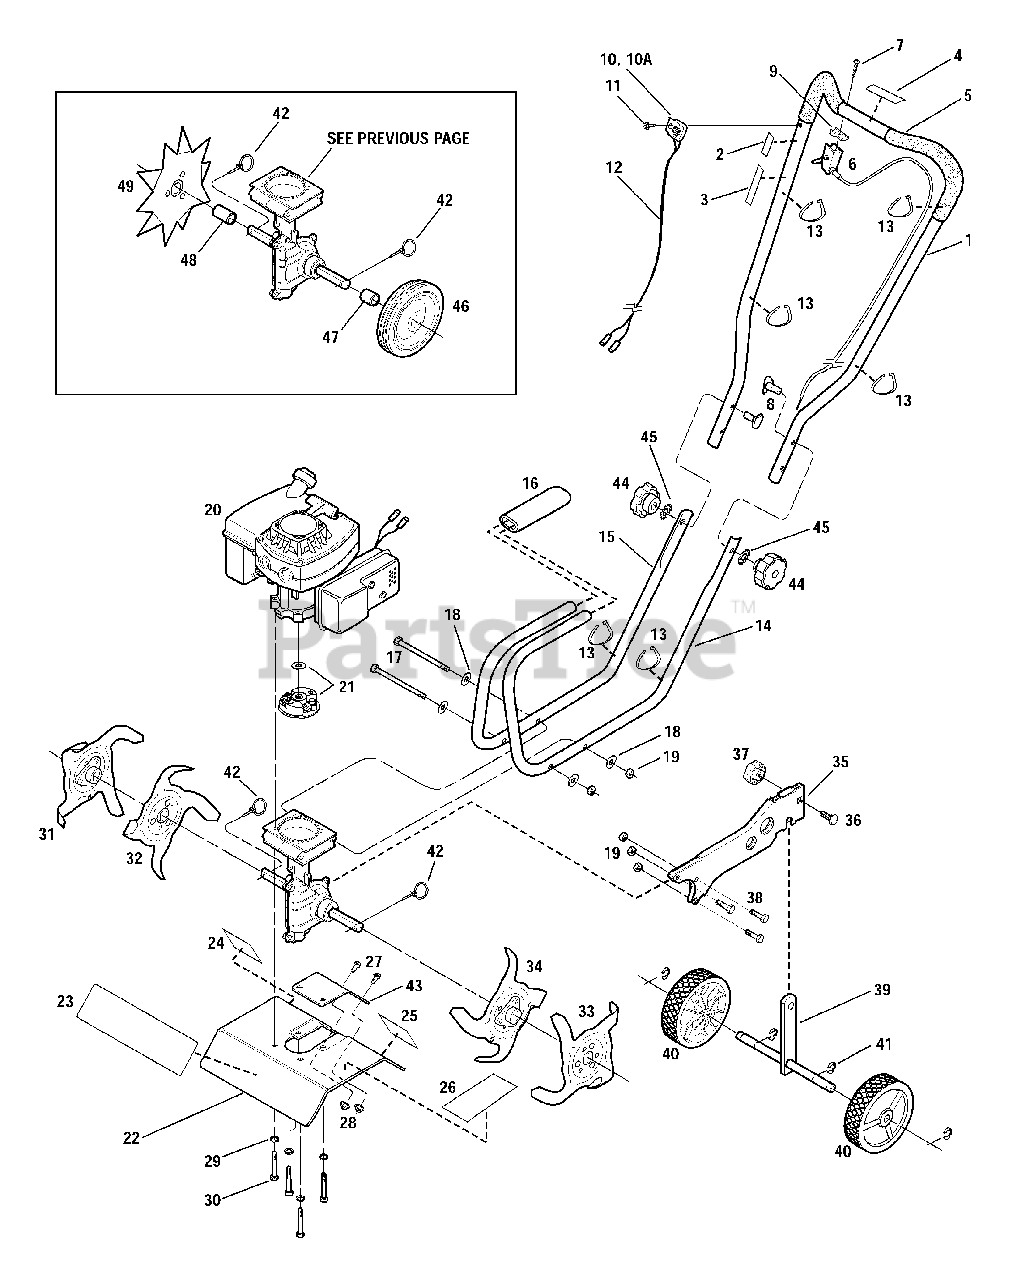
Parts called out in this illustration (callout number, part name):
1	Handlebar Assy.
2	Decal - On/Off Ignition Switch
3	Decal - Starting Stabilization
4	Decal - Throttle Lever Operation
5	Handlebar Grip, PVC
6	Throttle Lever and Cable
7	Pan Hd. Screw, #10-16 x 1-1/2
8	Saddle Hd. Screw, 5/16-18 x 2
9	Spacer, Throttle Lever
10	On/Off Ignition Switch
10A	Bracket - On/Off Ignition Switch
11	Phillips Hd. Screw, #12-24
12	Wire Assy. - On/Off Ignition Switch
13	Plastic Wire Tie
14	Lower Handlebar - Left-Side
15	Lower Handlebar - Right-Side
16	Foam Sleeve
17	Hex Hd. Screw, 1/4-20 x 5
18	Flat Washer, 1/4-20
19	Hex Locknut, 1/4-20
20	Engine
21	Clutch Rotor and Washer
22	Tine Shield
23	Decal - Logo
24	Decal - Warning, Rotating TInes
25	Decal - Warning, Hot Surfaces
26	Decal - Caution, Operation Hazards
27	Hex Hd. Screw, #10-24 x 1/2
28	Flange Locknut, #10-24
29	Lock Washer, 1/4-20
30	Hex Hd. Cap Screw, 1/4-20 x 2
31	Outer Tine - Right-Hand Side
32	Inner Tine - Right-Hand Side
33	Outer Tine - Left-Hand Side
34	Inner Tine - Left-Hand Side
35	Wheel Bracket
36	Carriage Bolt
38	Hex Hd. Screw, 1/4-20 x 1
40	Wheel
41	E-Ring
42	Ring Lock Pin
43	Tine Hood Cover
45	Lock Washer, 5/16
46	Edger Wheel
47	Bushing - Short
48	Bushing - Long
49	Edger Tine
